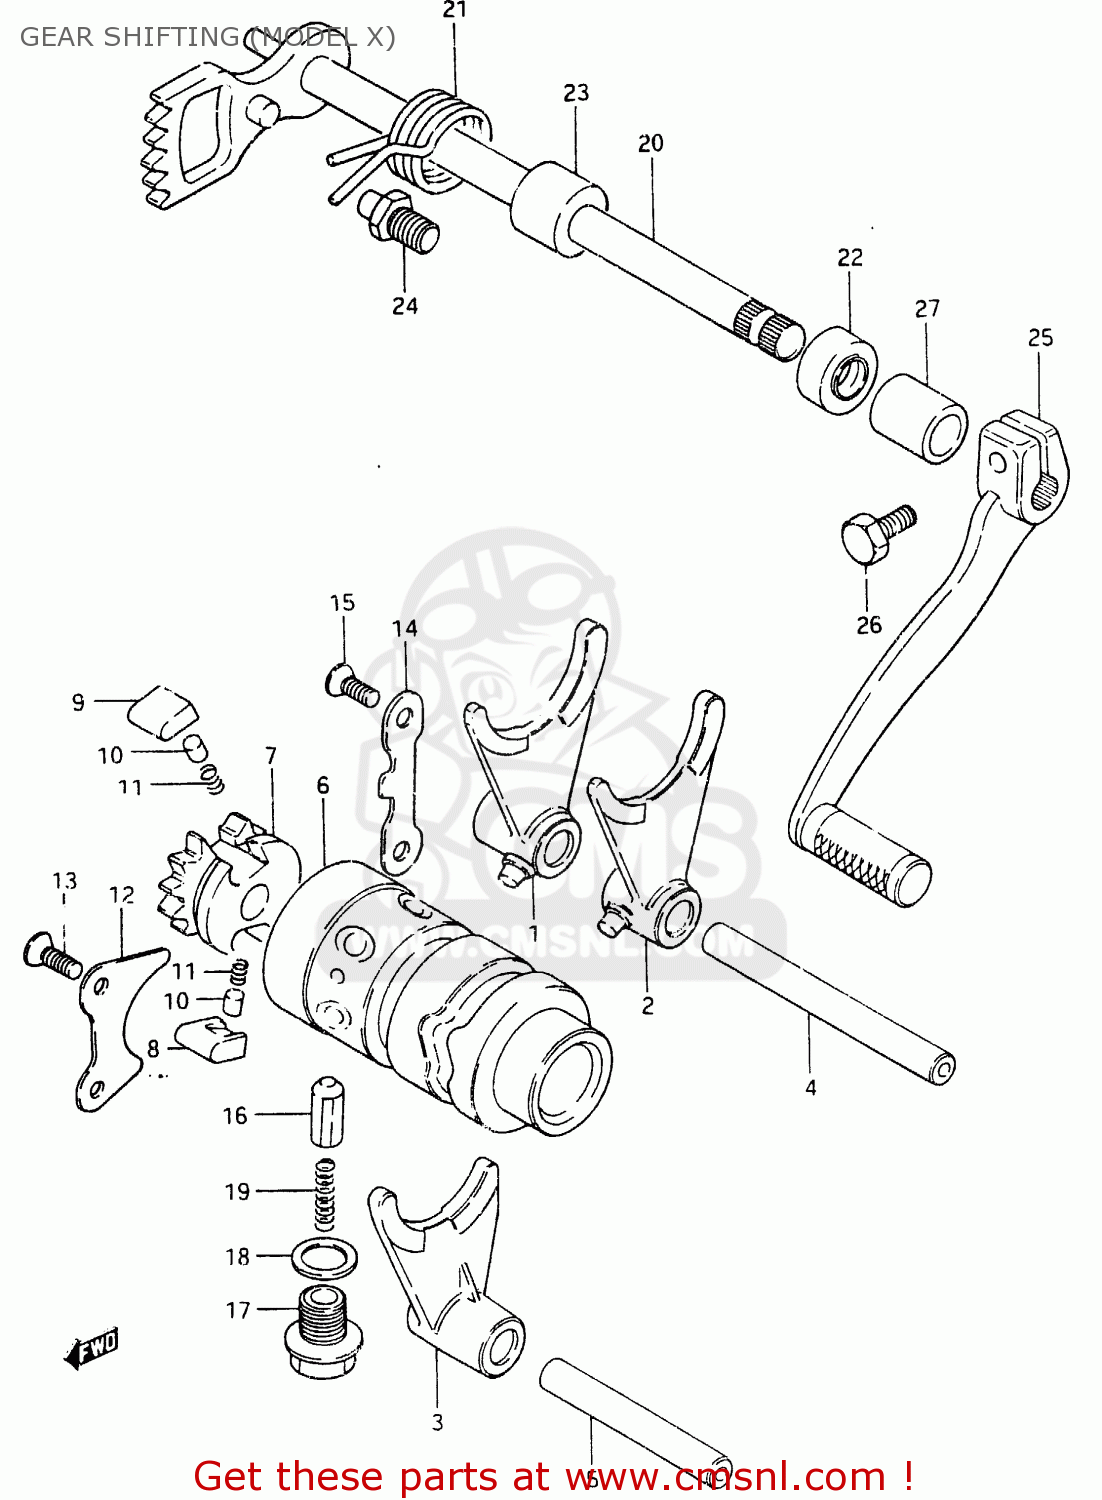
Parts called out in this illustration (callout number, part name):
1	FORK,GEAR SHIFT NO.1
2	FORK,GEAR SHIFT NO.2
3	FORK,GEAR SHIFT NO.3
4	SHAFT,GEAR SHIFT FORK
5	SHAFT,GEAR SHIFT FORK
6	CAM,GEAR SHIFT
7	RETAINER,GEAR SHIFT CAM
8	PAWL,GEAR SHIFT NO.1
9	PAWL,GEAR SHIFT NO.2
10	PIN(5X8)
11	SPRING
12	LIFTER,GEAR SHIFT PAWL
13	SCREW
14	GUIDE,GEAR SHIFT CAM
15	SCREW
16	STOPPER,GEAR SHIFTING
17	BOLT,GEAR SHAFT CAM STOPPER
18	GASKET(14X19.2X2) (NAS)
19	SPRING
20	SHAFT,GEAR SHIFT
21	SPRING
22	OIL SEAL
23	SPACER(12X20X15.3)
24	STOPPER,GEAR SHIFT CAM
25	LEVER,GEAR SHIFT
26	BOLT
27	CUSHION
